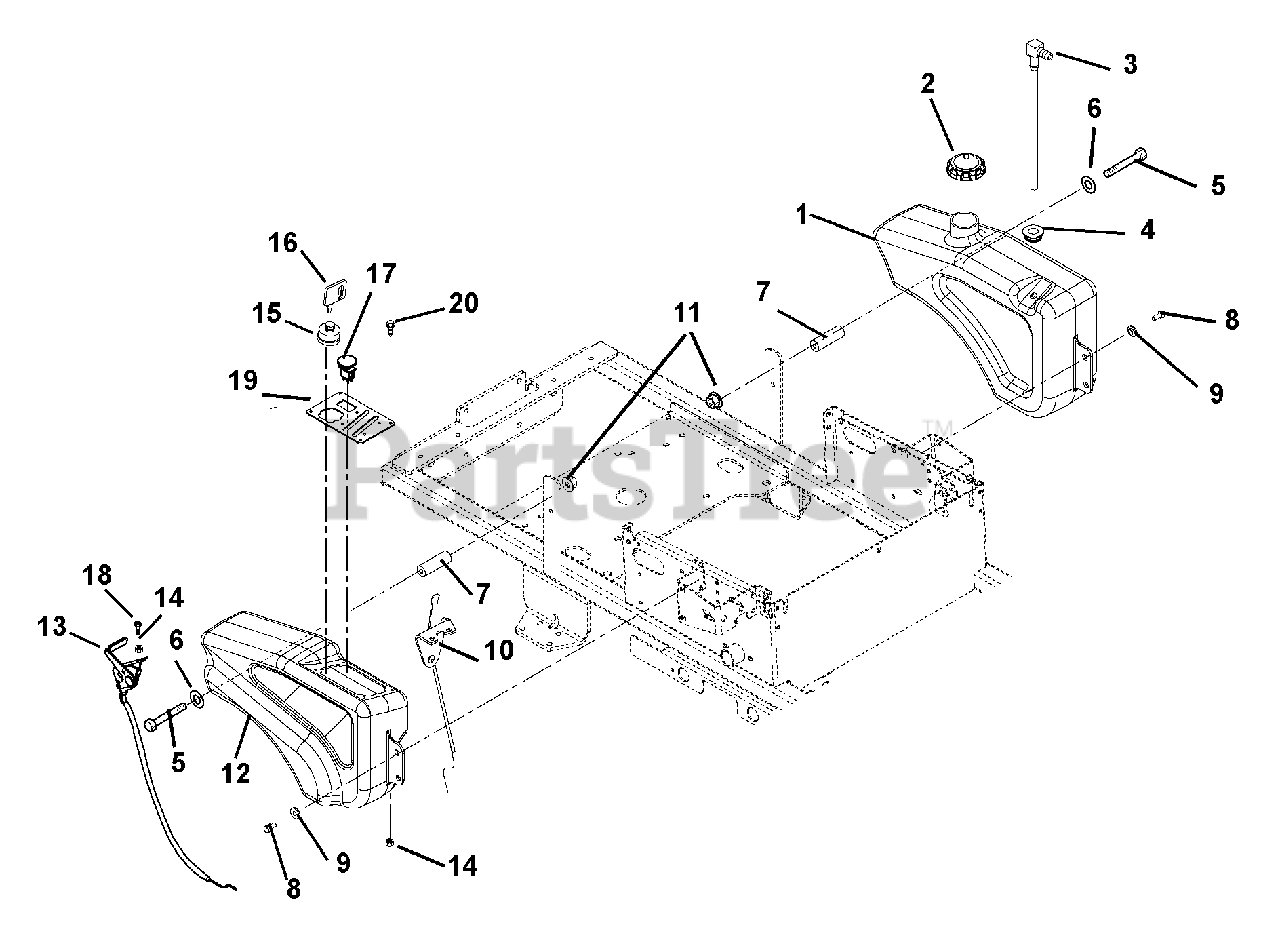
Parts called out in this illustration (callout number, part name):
1	GAS TANK, ZOOM
2	FUEL CAP
3	FITTING, TANK
4	BSHG-FLG .375 X 1.062 X .625 R
5	@BLT-HEX .31-18X3.50 GR5 YWZC
6	@WSHR-FL-STL.38X.875X.083 YWZC
7	SPCR, FLG .32X.49X.15X2.64
8	@BLT-HEX .31-18X.75 GR5 YWZC
9	BSHG, FLG .325X.499X.26X.88
10	CABLE, CHOKE CABLE
11	@NUT-LK-NYL-FLG .31-18 YWZC
12	FENDER, ZOOM
13	CABLE, ZOOM THROTTLE
14	@NUT-LK-NYL 10-24 W/INSRT YWZC
15	KEY SWITCH
16	KEY -W/CAP
17	SWITCH, CLUTCH
18	@SCR-MCH 10-24X.75 HWH YWZC
19	PANEL, ZOOM CONTROL
20	RIVET, PLASTIC .195 DIA.
